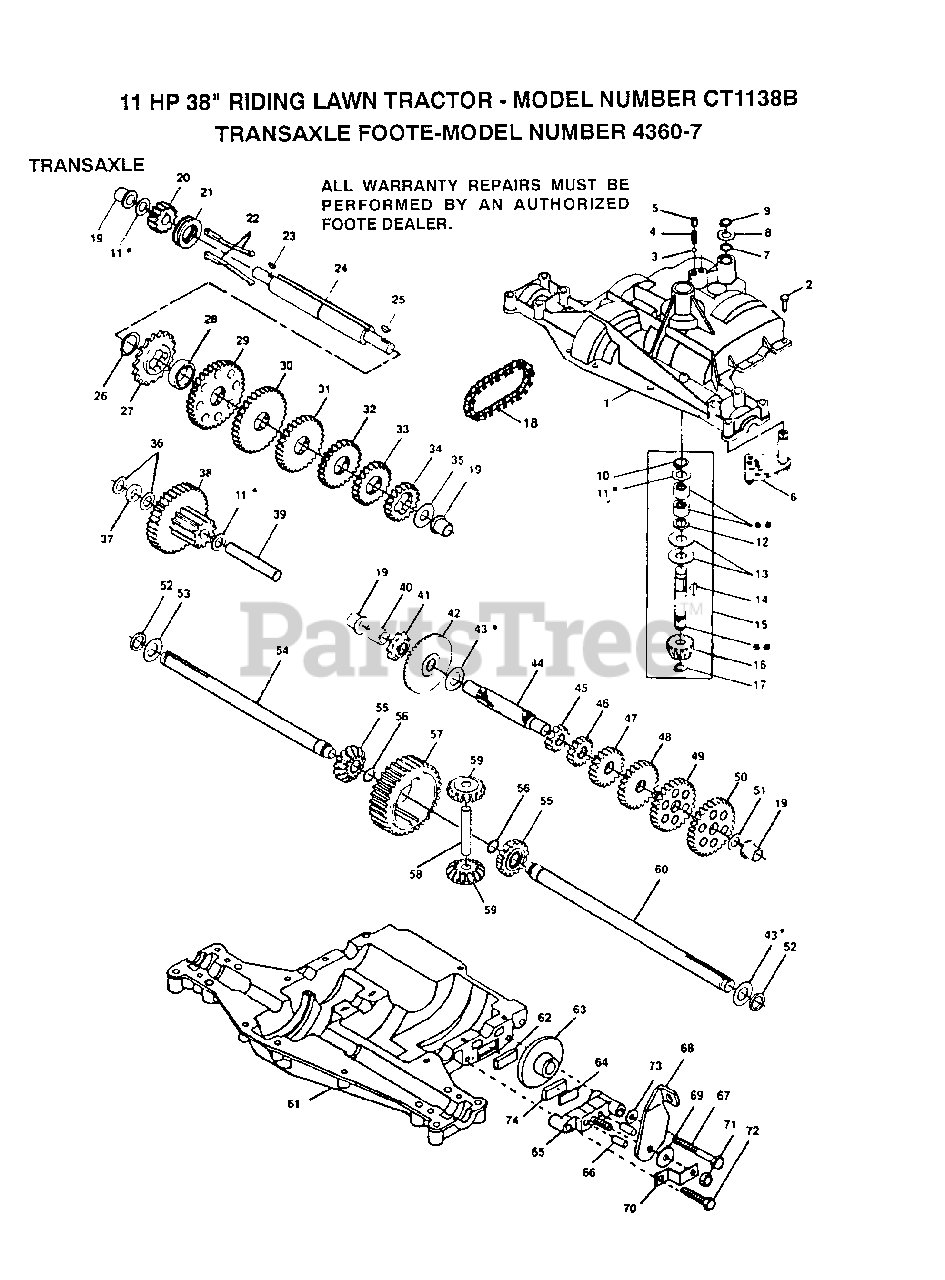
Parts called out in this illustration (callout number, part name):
1	HOUSING UPPER
3	BALL DETENT
4	SPRING, DETENT
5	SCREW, SET
6	ASSY SHIFTER
8	WASHER PLAIN
9	RING RETAINING
10	RING RETAINING
11	WASHER PLAIN
13	WASHER, PLAIN .632 X 1.38 X .046
14	KEY WOODRUFF #9
15	ASSY KIT INPUT SHAFT
16	PINION, BEVEL, 14 TEETH
17	RING, RETAINING
18	CHAIN, 24 PITCHES
19	BEARING, FLANGE
20	GEAR SPUR, 14 TEETH
21	COLLAR CLUTCH
22	KEY CLUTCH
23	KEY WOODRUFF #3
24	SHAFT INTERMEDIATE
25	KEY, WOODRUFF, #61
26	RING, RETAINING
27	SPROCKET, 18 TEETH
29	GEAR, SPUR, 37 TEETH
30	GEAR, SPUR, 35 TEETH
31	GEAR, SPUR, 30 TEETH
32	GEAR, SPUR, 25 TEETH
33	GEAR, SPUR, 22 TEETH
35	WASHER, PLAIN .640 X 1.37 X .061
36	WASHER, PLAIN .632 X 1.00 X .026
37	SPACER .630 X 1.00 X .169
38	ASSY GEAR COMB 12&35 TEETH
39	SHAFT IDLER
40	SPACER .635 X .875 X .755
41	SPROCKET, 9 TEETH
42	GEAR, BEVEL, 42 TEETH
43	WASHER PLAIN
44	SHAFT, DRIVE
45	GEAR, SPUR, 12 TEETH
46	GEAR SPUR, 15 TEETH
47	GEAR, SPUR, 20 TEETH
48	GEAR, SPUR, 25 TEETH
49	GEAR, SPUR, 28 TEETH
50	GEAR, SPUR, 31 TEETH
51	WASHER, PLAIN .632 X 1.00 X .060
53	WASHER PLAIN
54	AXLE LEFT HAND
55	GEAR, MITER, 15 TEETH
56	RING, RETAINING
57	GEAR, SPUR, 32 TEETH
58	SHAFT, CROSS
59	GEAR, MITER, 15 TEETH
60	AXLE, R.H.
61	HOUSING LOWER
62	PUCK, FRICTION
63	DISC, BRAKE
65	JAW, BRAKE
66	PIN, DOWEL
67	SCREW TAPPING
68	LEVER, ACTUATING
69	WASHER, PLAIN .321 X 1.00 X .055
70	BRACKET, ANTI-ROTATION
71	LOCKNUT 5/16-24
72	SCREW TAPPING
73	WASHER PLAIN
74	PUCK, FRICTION
